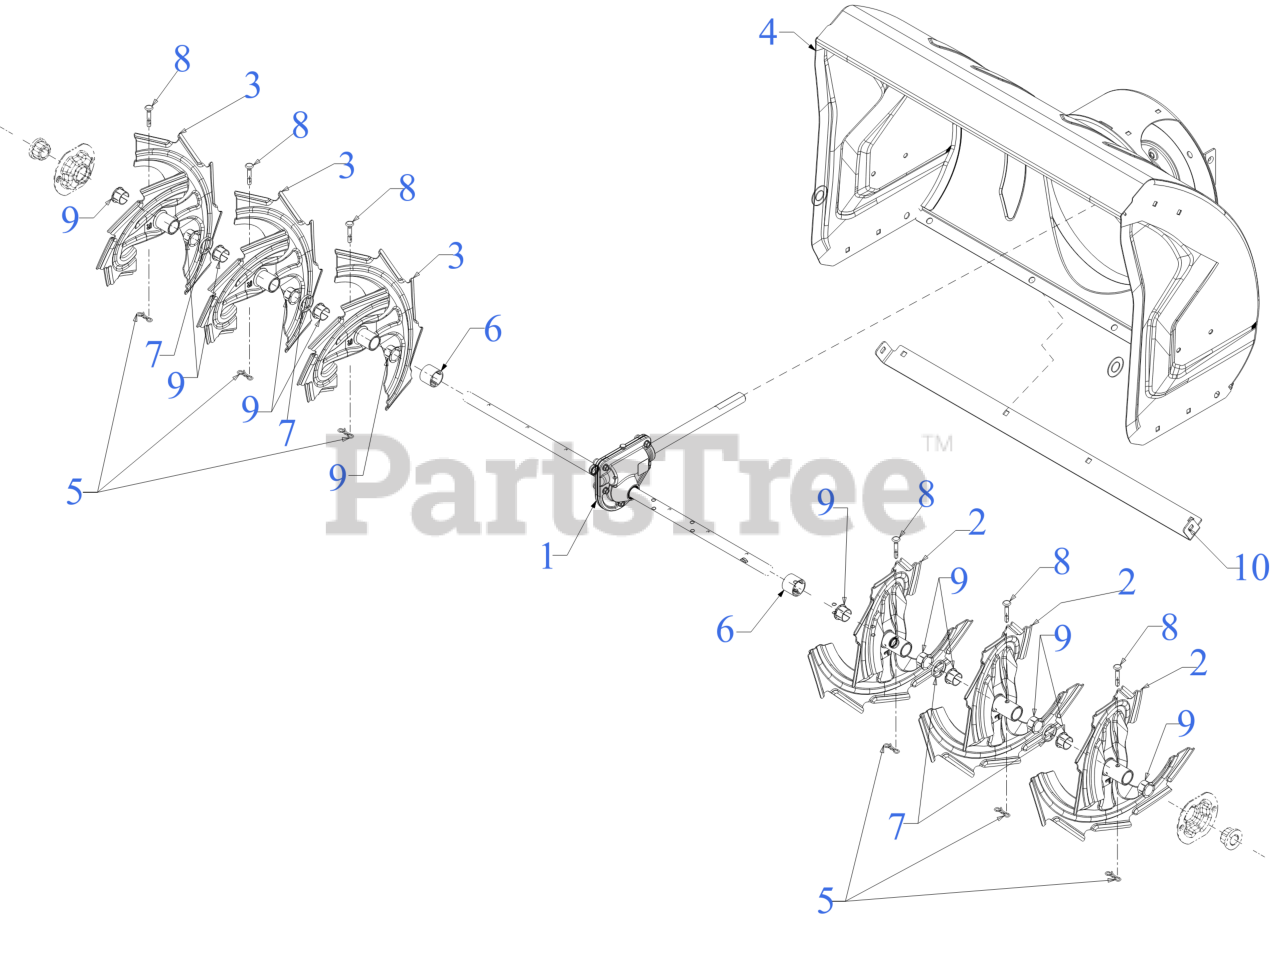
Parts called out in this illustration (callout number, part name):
1	AUGER GEARBOX ASSEMBLY 30"
2	10T AUGER SPIRAL (LH)
3	10T AUGER SPIRAL (RH)
4	30" AUGER HOUSING
5	BOW TIE COTTER PIN 1/4-5/16
6	SPACER 1.25OD x .75ID X1.00 LG
7	SPCR 1.25 OD x 75IDX2.00LG
8	SHEAR PIN .25 x 1.50 GR2
9	FLANGE BUSHING
10	30" SHAVE PLATE
